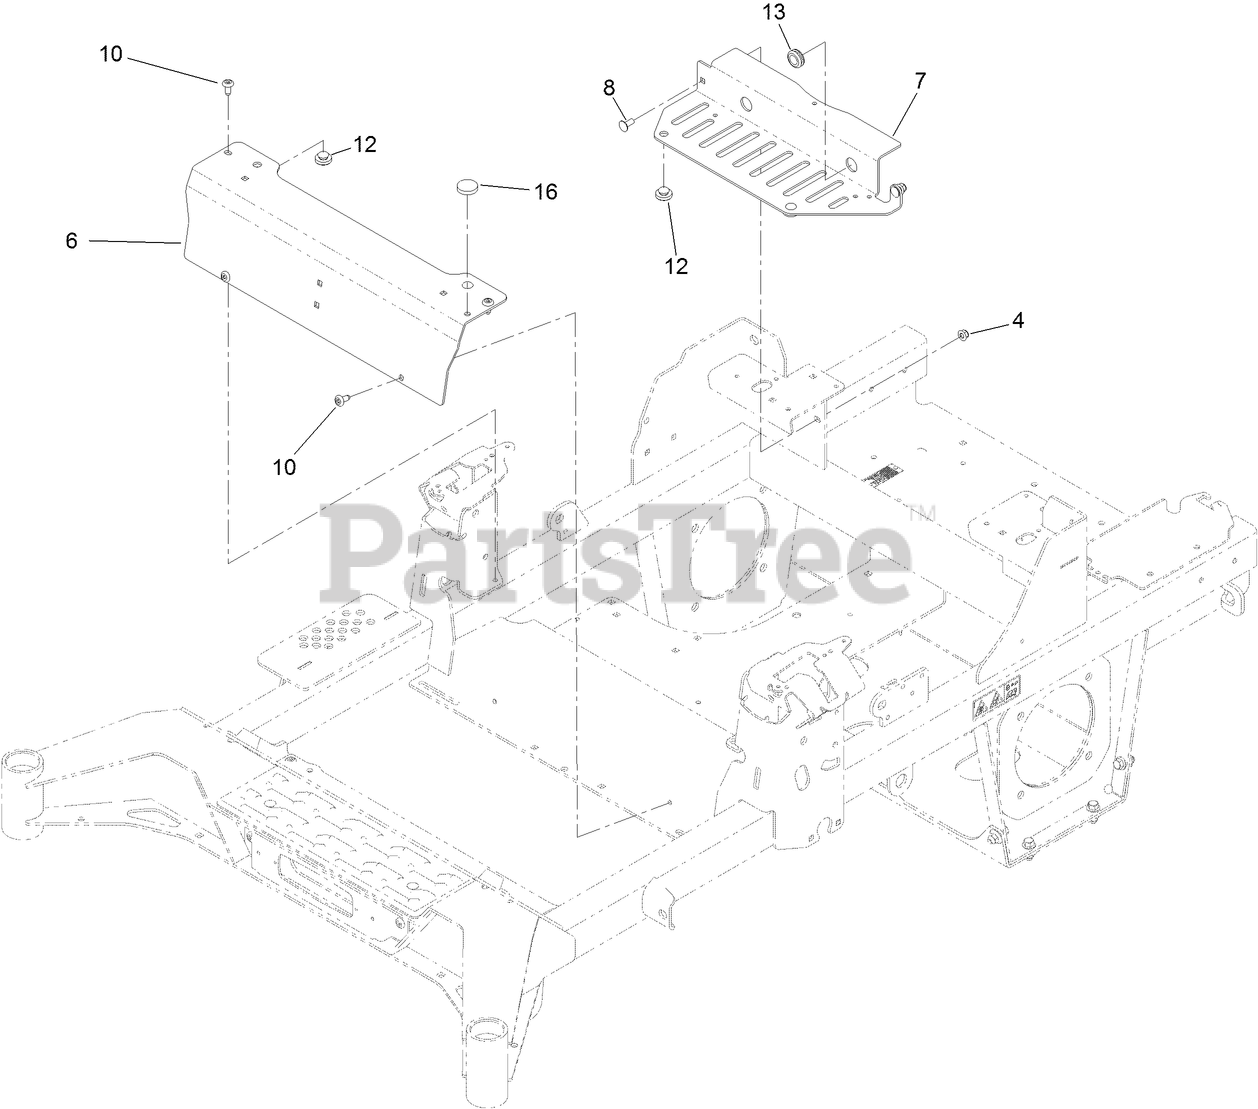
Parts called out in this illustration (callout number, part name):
4	NUT-HF, NI
6	PLATE-TANK RETAINER, FRONT
7	PLATE-TANK RETAINER, REAR
8	SCREW-CARR
12	BUMPER-SEAT
13	GROMMET
16	BUMPER-PUSH-IN, RUBBER
